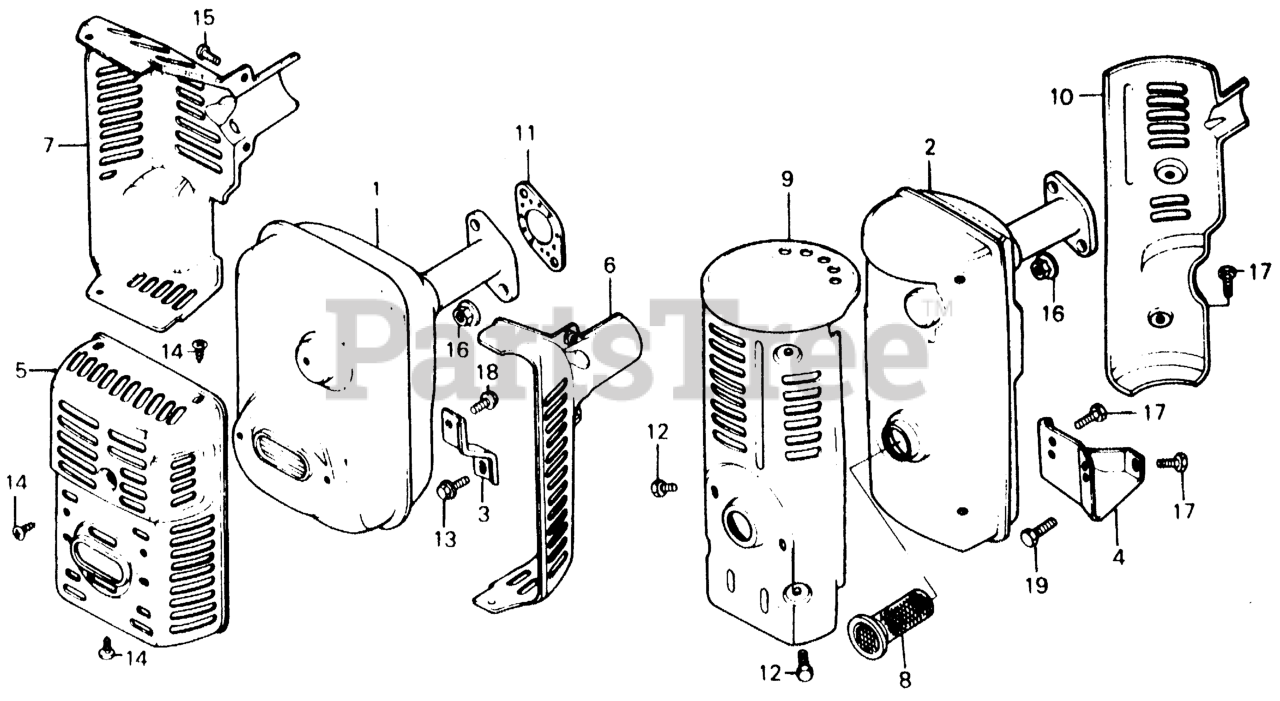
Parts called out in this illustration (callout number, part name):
1	MUFFLER
2	MUFFLER (ARRESTER)
3	STAY, MUFFLER
4	STAY, MUFFLER
5	PROTECTOR, FR. MUFFLER
6	PROTECTOR, R. MUFFLER
7	PROTECTOR, L. MUFFLER
8	ARRESTER, SPARK
9	PROTECTOR A, MUFFLER
10	PROTECTOR B, MUFFLER
11	GASKET, MUFFLER
12	BOLT-WASHER (6X10)
13	BOLT, FLANGE (6X12) (CT200)
14	SCREW, TAPPING (4X6) (TO INSTALL OPTIONAL SPARK ARRESTER)
15	SCREW, PAN (4X6) Use from Engine SN 1012895 to 1428861.
16	NUT, FLANGE (8MM)
17	BOLT, FLANGE (6X10)
18	BOLT, FLANGE (6X10)
19	BOLT, FLANGE (8X16)
